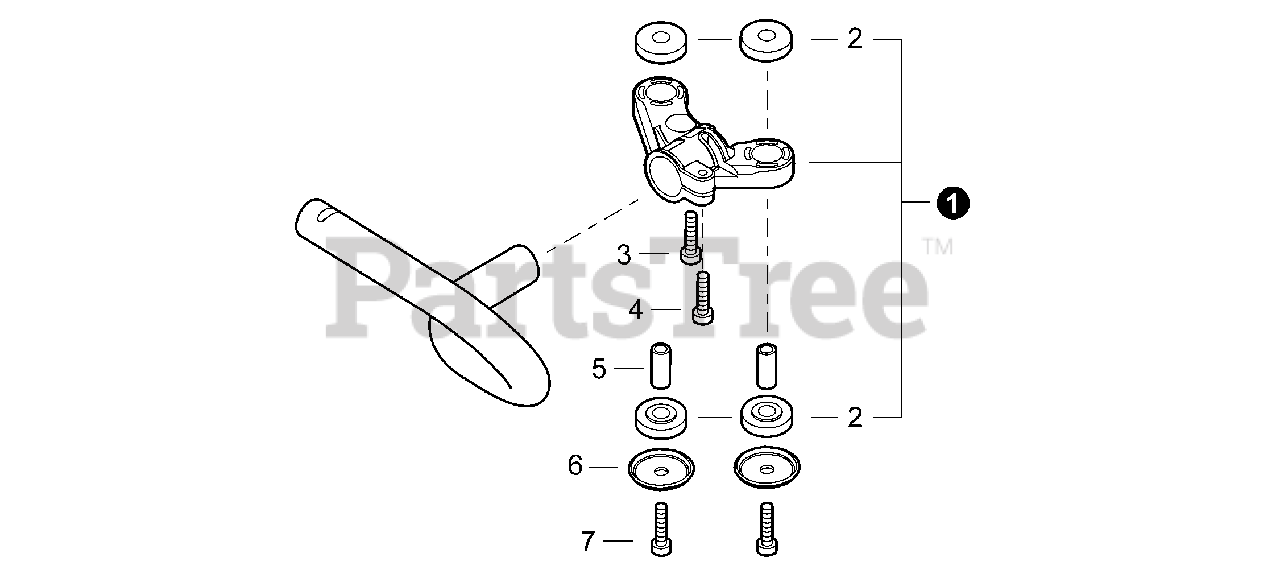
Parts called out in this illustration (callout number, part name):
1	SUPPORT ASSY, HANDLE
2	CUSHION
3	BOLT, TORX 5×12
4	BOLT, TORX 5×16
5	COLLAR 6
6	WASHER 6
7	BOLT, TORX 6
